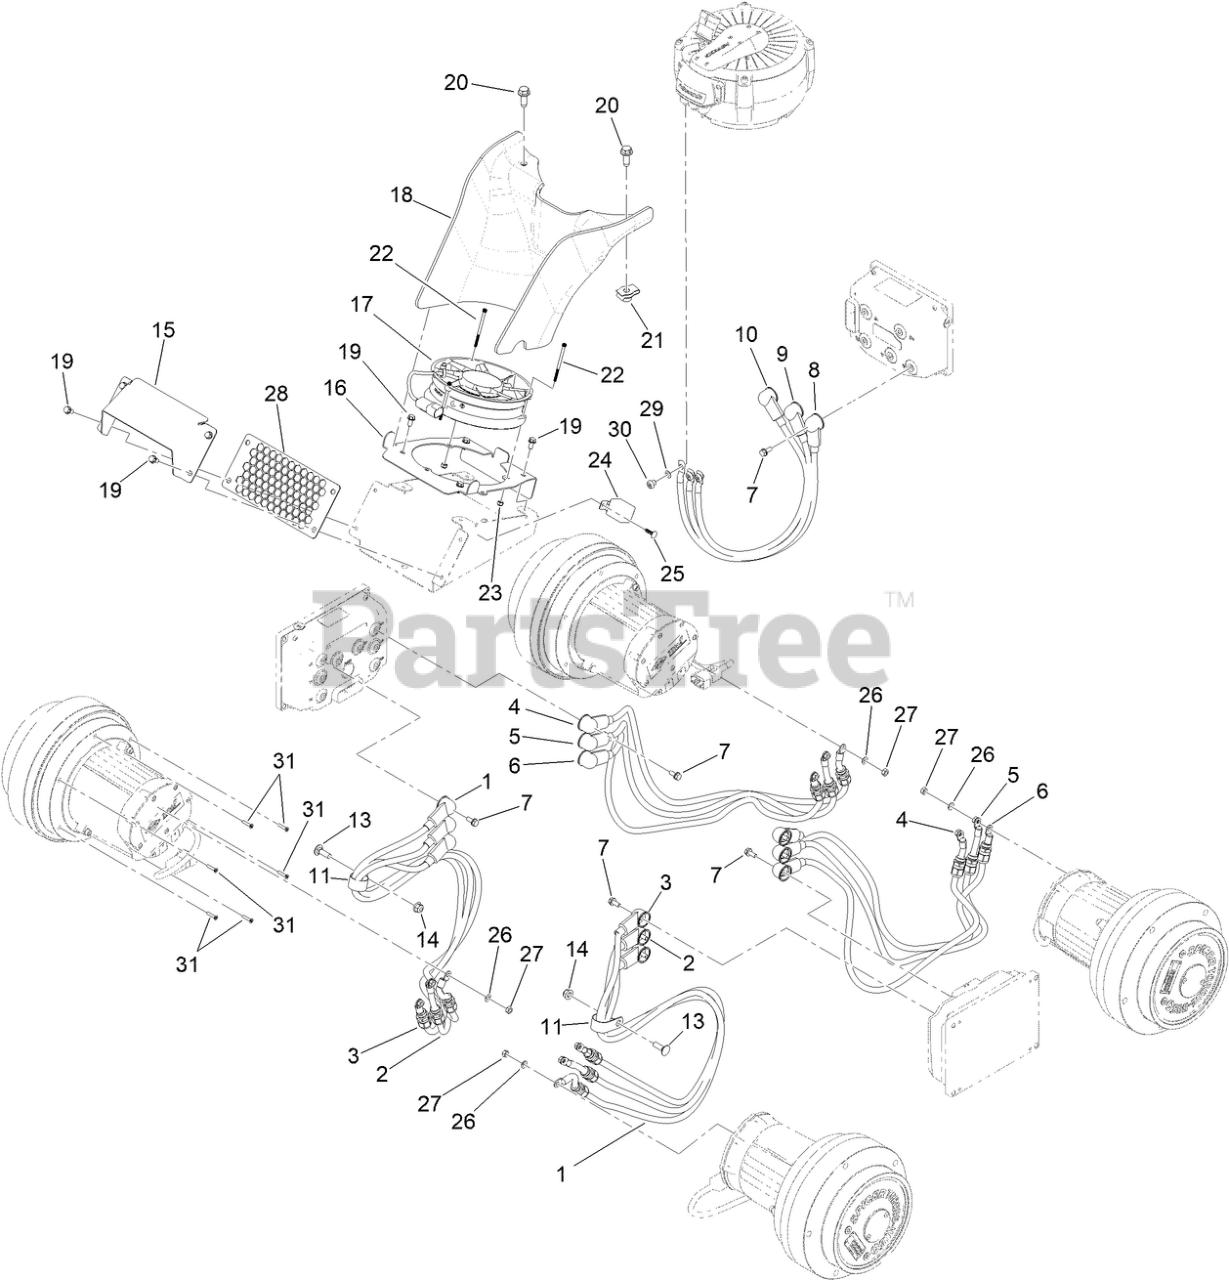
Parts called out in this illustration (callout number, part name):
1	CABLE-BATTERY, RD ASM
2	CABLE-BATTERY, RD ASM
3	CABLE-BATTERY, RD ASM
4	CABLE-BATTERY, RD ASM
5	CABLE-BATTERY, RD ASM
6	CABLE-BATTERY, RD ASM
7	SCREW-SEMS
8	CABLE-BATTERY, RD ASM
9	CABLE-BATTERY, RD ASM
10	CABLE-BATTERY, RD ASM
11	R-CLAMP
13	BOLT-CARR
14	NUT-HF, NI
15	DEFLECTOR-FAN
16	PLATE-ADAPTER,FAN
17	FAN-48V, 6.8"
18	SHROUD-FAN
19	SCREW-HWH
20	SCREW-HWH
21	NUT-TINNERMAN
22	SCREW-HSH
23	NUT-LOCK
24	RELAY, 48V COIL, 50A AT 48V
25	PLUG-PLASTIC
26	WASHER-SPRING
27	NUT-HEX
28	SCREEN - FAN GUARD
29	WASHER-BELLEVILLE
30	SCREW-HSBH
31	SCREW-TFH
